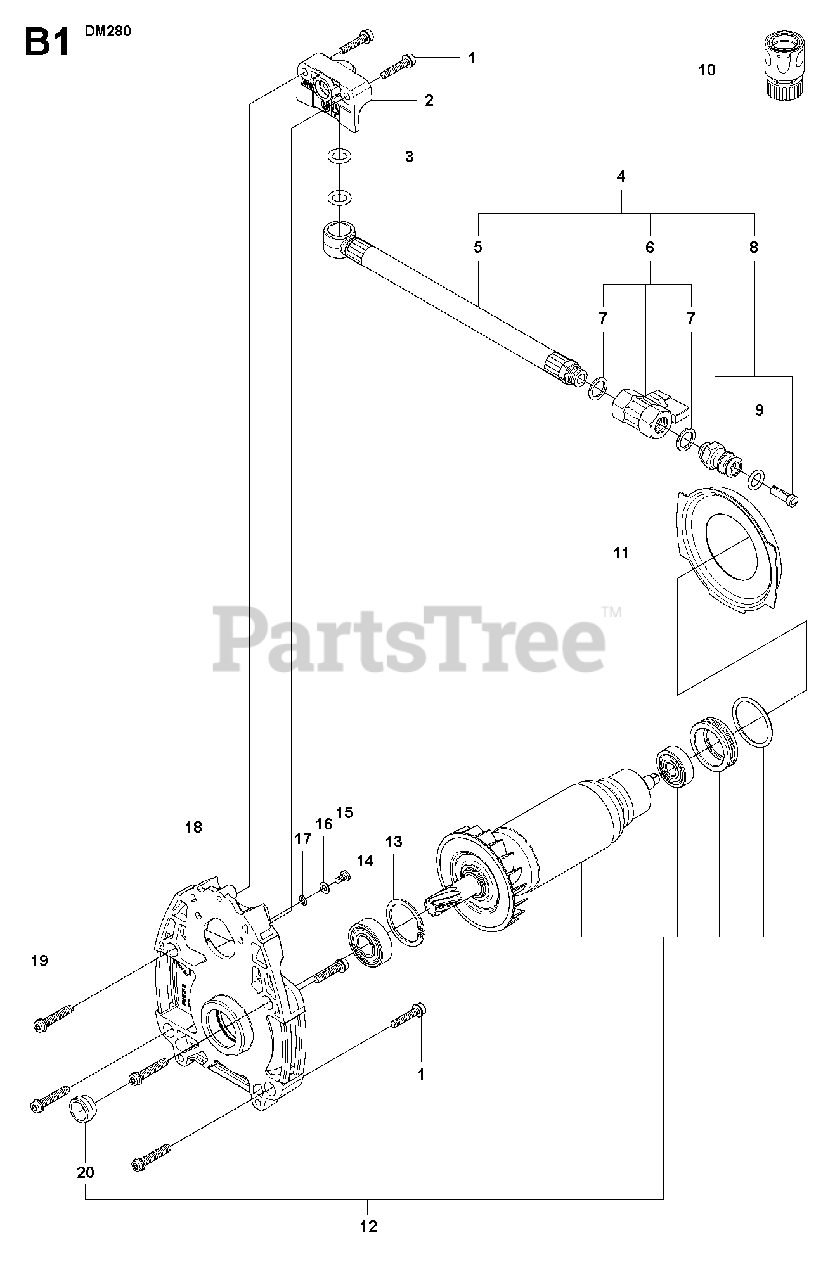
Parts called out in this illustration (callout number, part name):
1	SCREW IHSCFM
4	HOSE ASSYIncl 5, 6, 8
6	VALVE KITIncl 7
8	NIPPLEIncl 9
10	COUPLERUS, CANADA
14	BALL BEARING
15	SCREW CRPANM
